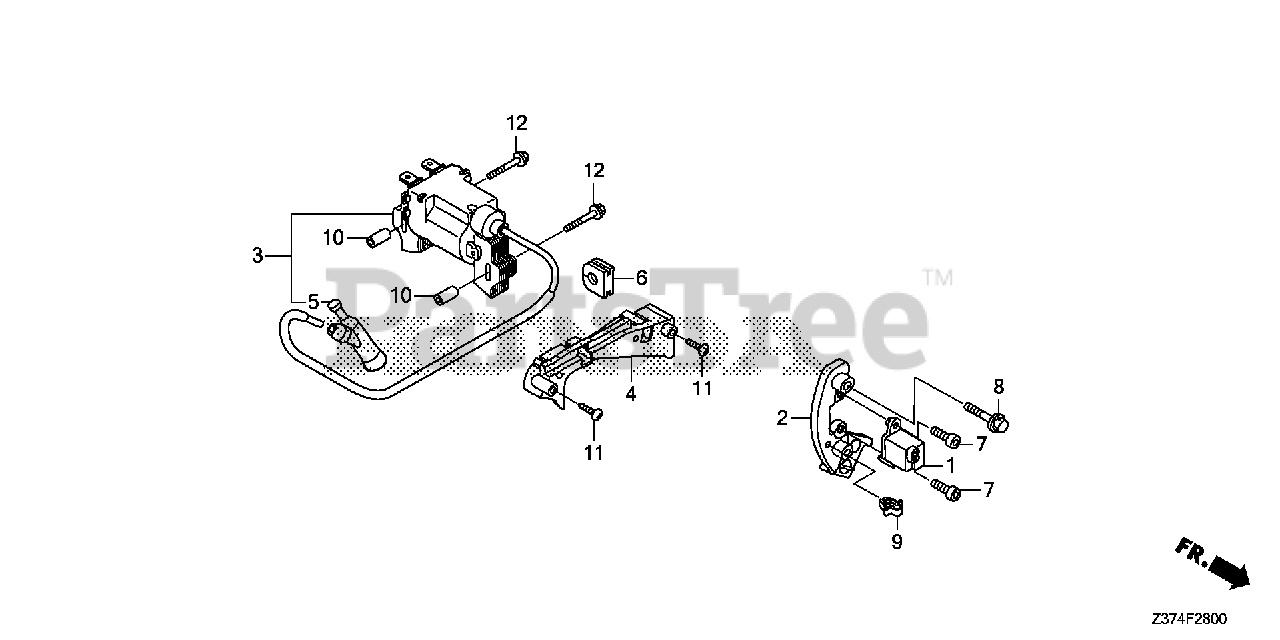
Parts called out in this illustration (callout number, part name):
1	GENERATOR ASSY., PULSE (TEC)
2	BRACKET, PULSER COIL
3	COIL ASSY., IGNITION
4	CLAMP, IGNITION WIRE
4	CLAMP, IGNITION WIRE (NOT AVAILABLE)
5	CAP ASSY., NOISE SUPPRESSOR (TEC)
6	GROMMET, WIRE
7	BOLT, SOCKET (5X14)
8	BOLT, FLANGE (6X25) Use up to Engine SN 2056819.
9	CLIP, ENGINE STOP SWITCH CORD
10	COLLAR (6.6X13.8X14.5)
11	SCREW, TAPPING (5X16) (PO)
12	BOLT, FLANGE (6X45)
